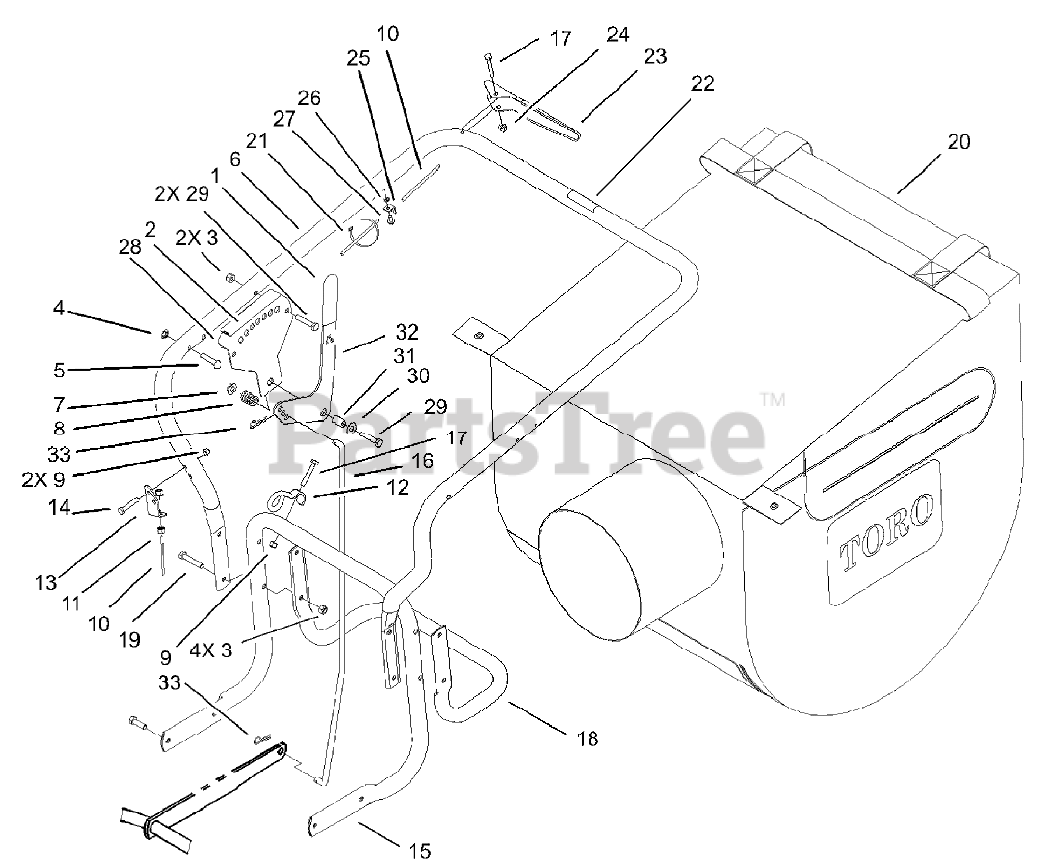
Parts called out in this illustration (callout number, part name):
1	GRIP-HANDLE
2	DECAL-ADJUSTMENT, HEIGHT
3	NUT-LOCK, NI
4	NUT-PUSH IN
5	RIVET
6	HANDLE-UPPER, VACUUM
7	NUT-HF
8	SPRING-COMPRESSION
9	NUT-LOCK, NI
10	CABLE-TRACTION
11	NUT-KEPS
12	GUIDE-ROPE
13	MOUNT-BOWDEN, LOWER
14	SCREW-HH
15	HANDLE-LOWER
16	ROD-ADJUST, HEIGHT
17	SCREW-HH
18	SUPPORT-BAG
19	SCREW-HH
20	Bag-Vacuum
21	TIE-CABLE
22	DECAL-CONTROL, TRACTION
23	LEVER
24	NUT-CAP
25	RETAINING-CLIP
26	WASHER-LOCK, EXT
27	SCREW-HWH
28	BRACKET-ADJUSTMENT
29	SCREW-HH
30	WASHER-FLAT
31	SPACER
32	HANDLE-ADJUST, HEIGHT
33	PIN-COTTER
